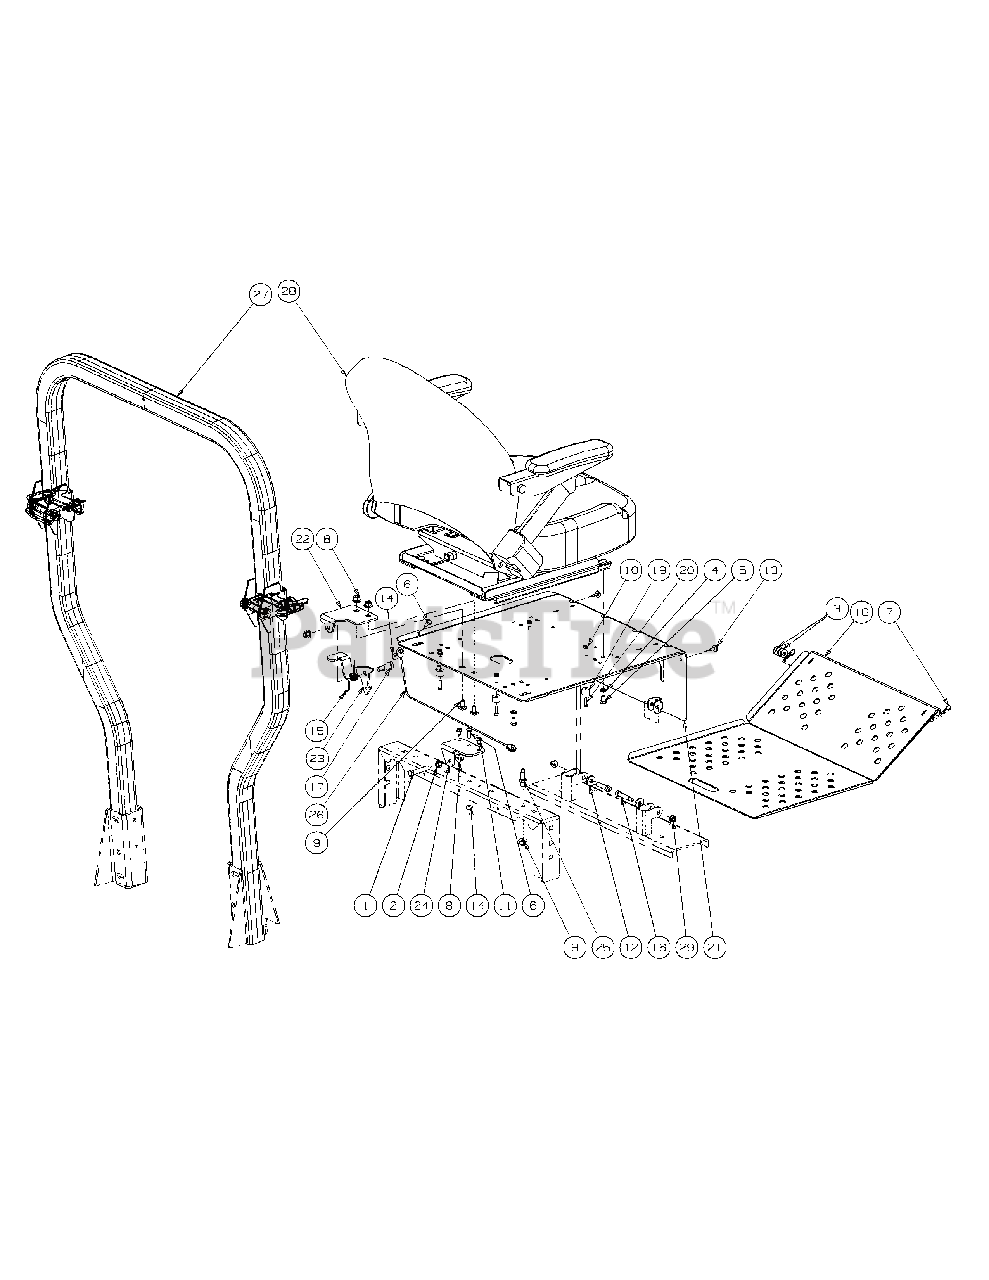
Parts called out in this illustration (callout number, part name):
1	Hex Cap Screw 3/8-16 x 2.00
2	Hex Nut, 3/8-16
4	Lock Washer, 5/16
5	Hex Cap Screw, 5/16-18 x 1/2
6	Screw, Hex, Cap, 1/4-20 x .75
7	Hair Pin, 3/8-1/2
8	Flange Lock, Hex Nut, 3/8-16
9	Carriage Bolt, 3/8-16 x .75 Long
10	Nut, #10-24, Nylon Lock
11	Screw, TT, 1/4-20, 0.5, Hex Index Washer
12	Flat Washer, .406 ID, 1.0 OD, .105
13	Rubber Bumper, .62 OD x .22 Thick
14	Lock Nut, 1/4-20
15	Deck Lift Spring, Left Hand
16	Shoulder Bolt, .375 x 1.50
17	Shoulder Bolt, 1/2 x 3/4, 3/8-16
18	Floor Panel Assembly
19	Rubber Stop with Washer
20	Standard Cap Screw, #10-24 x .75
21	Seat Plate Assembly
22	Seat Latch Bracket
23	Latch Lever Bracket
24	Latch Bracket
25	Adjustable Stud
26	Cable Support
27	Foldable Rops Assembly includes:
27	Knob
27	Pin, Lock
28	Seat w/ Seat Belt & Suspension
28	Armrest Kit
28	Seat Back Cover
28	Seat Bottom Cover
28	Seat Switch Assembly
29	Flange Lock Nut, 5/16-18
